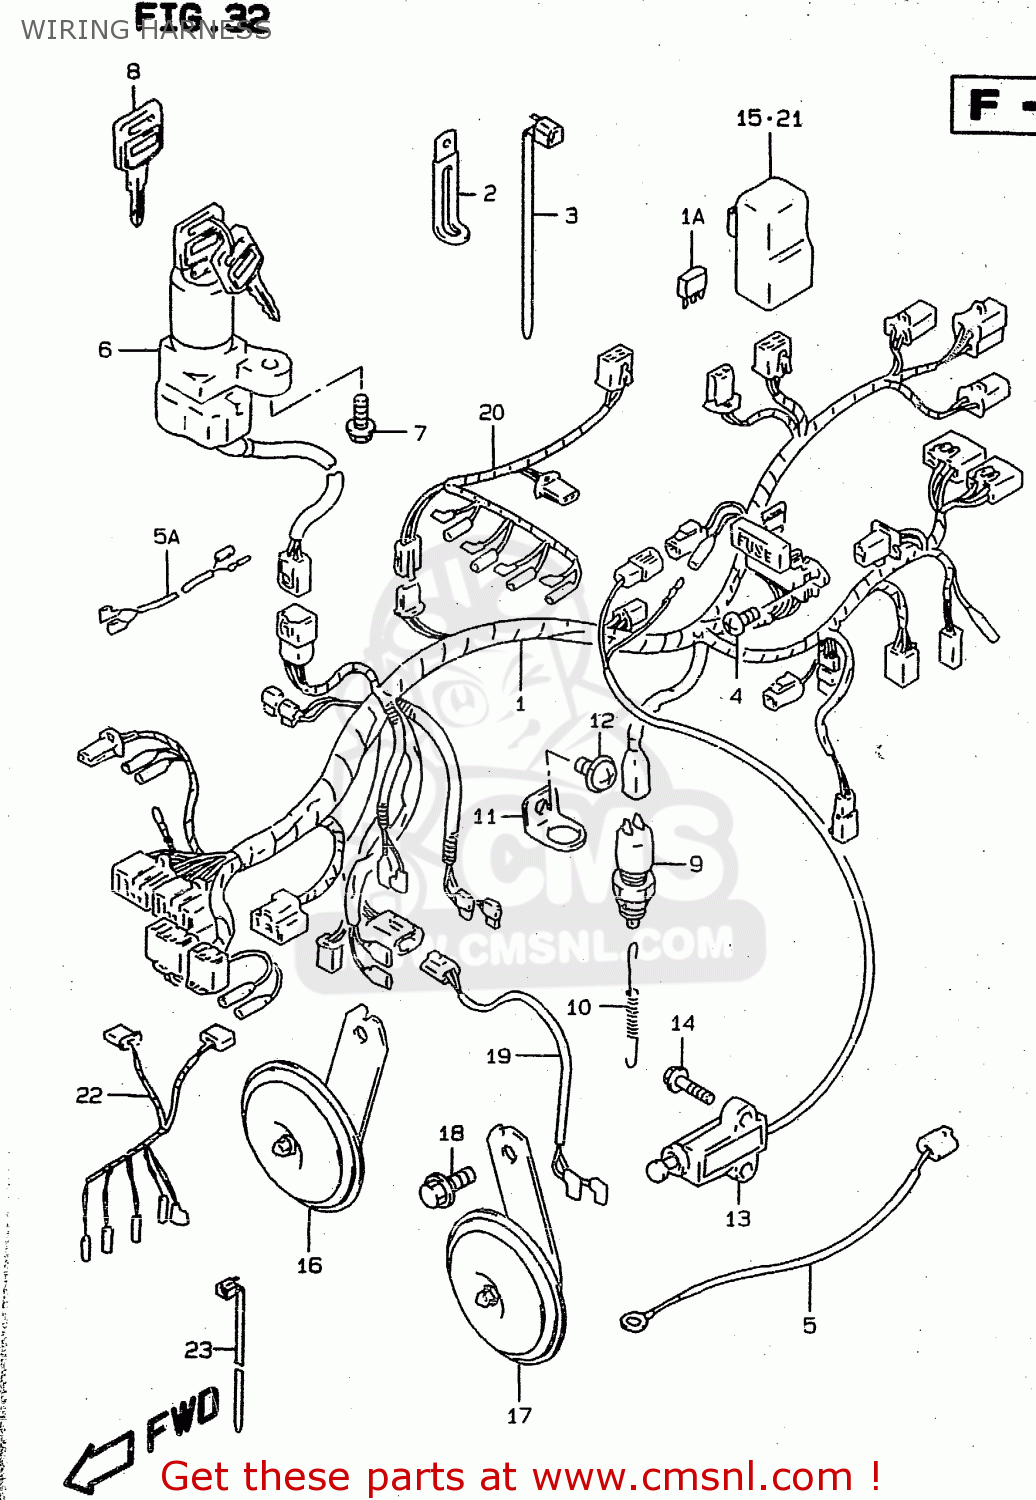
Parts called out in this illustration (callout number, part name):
1	HARNESS,WIRING
1A	DIODE(STANLEY DE8804)
2	CLAMP
3	CLAMP(L:90)
4	SCREW 6X12
5	WIRE,OIL PRESSURE SWITCH LEAD
5A	WIRE,CLUTCH LEAD
6	LOCK ASSY,STEE
7	SCREW(6X18)
8	KEY,BLANK
9	SWITCH ASSY,STOP LAMP
10	SPRING
11	BRACKET,STOP LAMP SWITCH
12	SCREW
13	SWITCH ASSY,SIDE STAND
14	BOLT
15	RELAY ASSY
16	HORN ASSY
17	HORN ASSY
18	BOLT
19	WIRE,HORN LEAD
20	WIRE,CARBURETOR HEATER LEAD
21	RELAY ASSY
22	WIRE, CARB HEATER LEAD
23	CLAMP(L:95)
